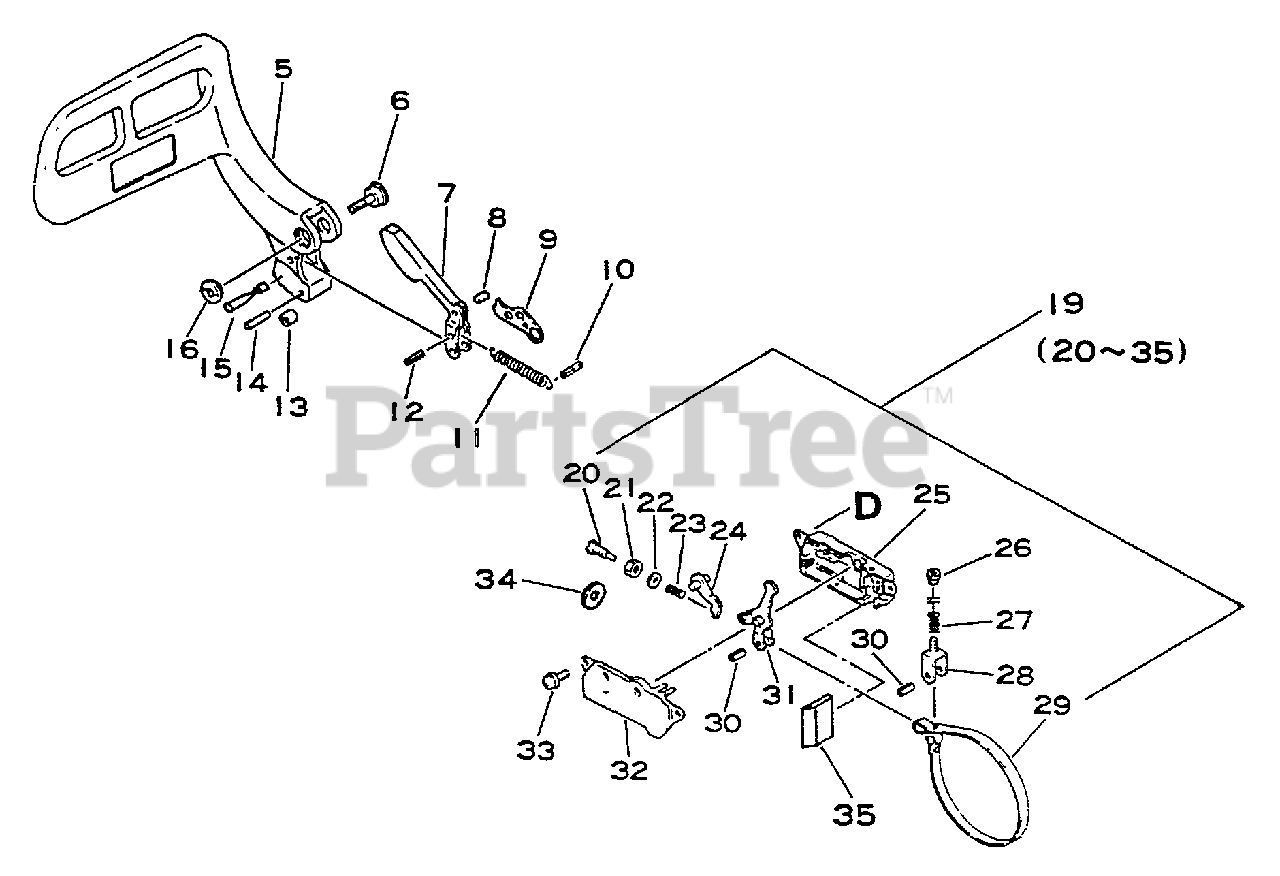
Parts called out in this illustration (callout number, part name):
5	LEVER, BRAKE
7	WEIGHT, BRAKE
8	PIN - LOCATING
9	STOPPER
10	PIN - SPRING -- 3X20
11	SPRING, RETURN
12	PIN - SPRING -- 3X12
13	SPACER
14	PIN - LOCATING
15	PIN - 3X24
19	CHAIN BRAKE ASSY
23	SPRING, BRAKE
24	STOPPER, BRAKE
25	COVER, BRAKE
28	ADJUSTER, BRAKE BAND
29	BAND, BRAKE
30	PIN - SPRING
31	LEVER, BRAKE
32	COVER, BRAKE
33	SCREW - 4X10
34	WASHER - 5
